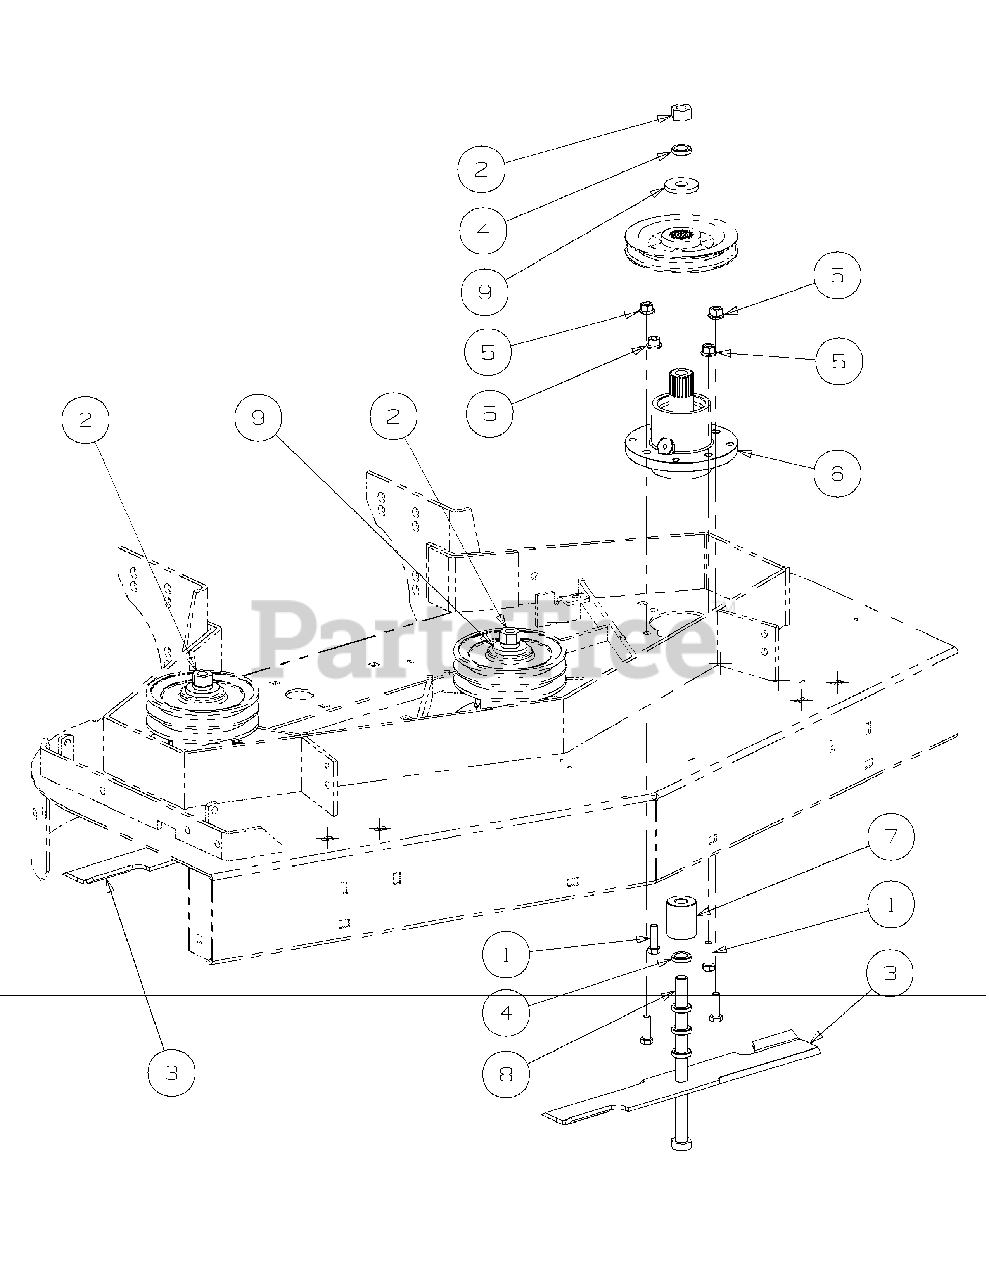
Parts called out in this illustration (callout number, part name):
1	Hex Cap Screw, 3/8-16 x 1-1/2
2	Hex Nut, 5/8-11
3	16 1/2" Rotary Blade
4	Blade Spacer, 5/8 ID, 1/4 Thick
5	Hex Nut Flange Lock, 3/8-16
6	Spindle Assembly
6	Grease Fitting, 1/4-28 x 1.609
7	Blade Spacer, .630 x 1.500 x 1.850
8	Hex Cap Screw, 5/8-11 x 9
9	Flat Washer, .656 ID x 1.313 OD
